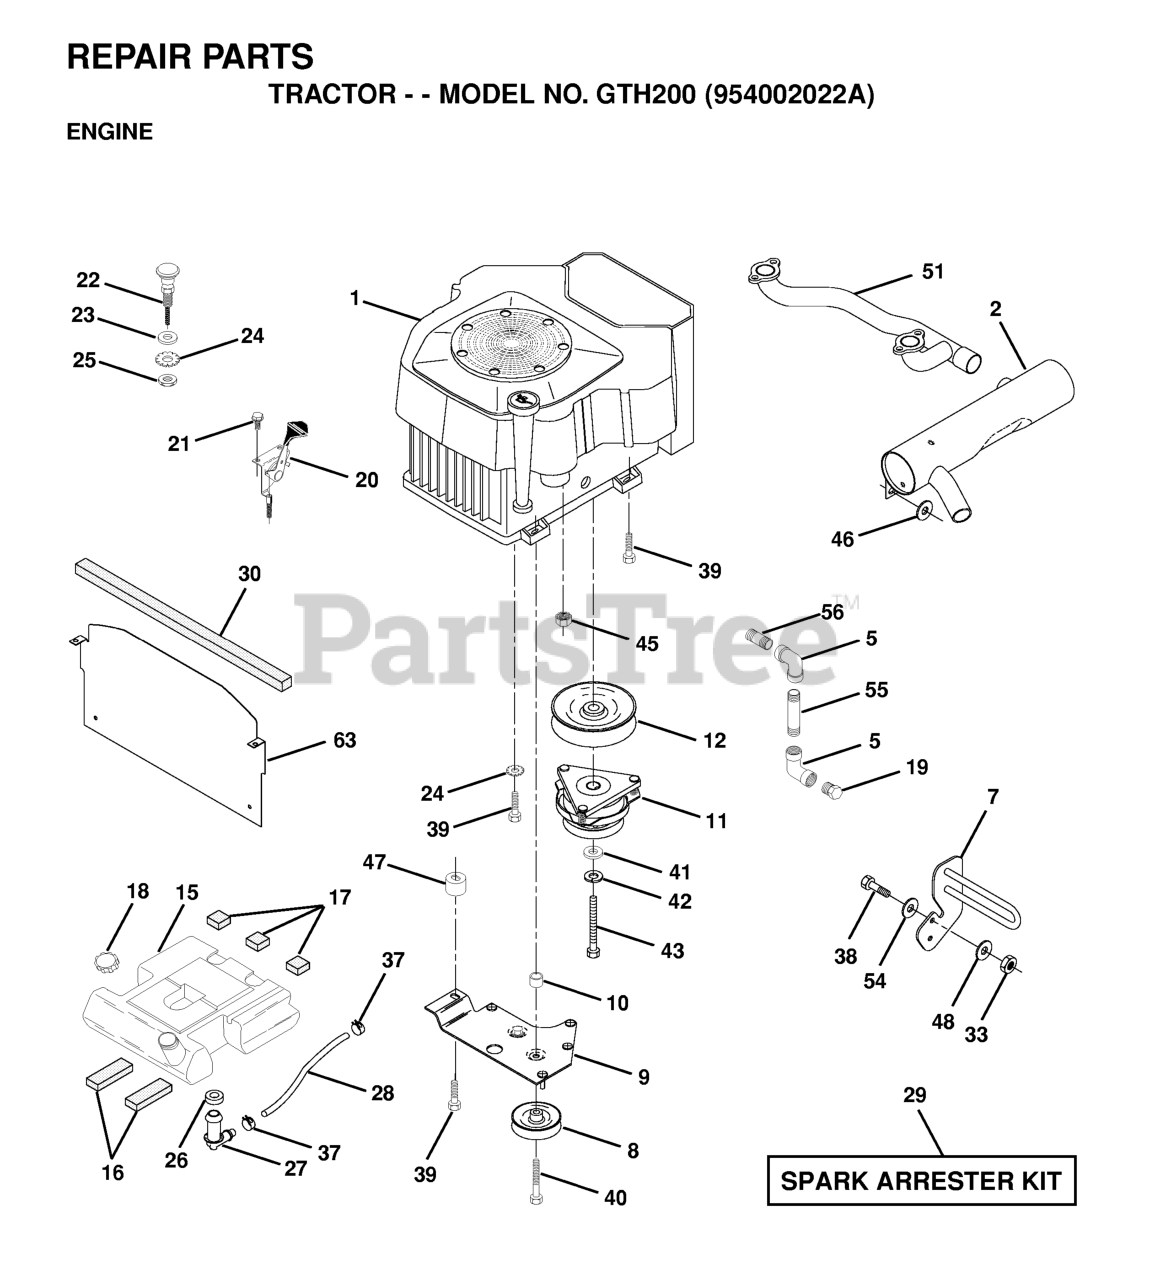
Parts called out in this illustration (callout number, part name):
2	MUFFLER VGT CYLINDER
5	ELBOW
7	MUFFLER GUARD
8	RP.IDLER GROOVED
9	BELT KEEPER
11	CLUTCH ELECTRIC
12	PULLEY ENG VGT ELECT CLUTCH
15	FUEL TANK REAR YT/GT
16	PAD IDLER TI
17	PAD-SPACER LT
18	FUEL CAP
20	THROTTLE CONTROL
21	SCREW LT
22	CHOKE CONTROL
23	WASHER
24	LOCKWASHER
25	NUT
26	BUSHING OUTLET T
27	STEM FUEL TANK
28	HOSE
29	SPARK ARRESTOR
30	FOAM-STRIP LT
33	NUT
37	HOSE CLAMP
38	BOLT
39	SCREW TT 3/8-16X2-1/4 UNC
40	Screw TT 3/8-16 x 4 unc
42	LOCKWASHER
43	BOLT
45	NUT FLANGE 1/4-20 STARTER NUT
46	WASHER
47	SPACER.ENGINE.CV22.ROUND.PM
48	Washer 13/32 x 1-1/4 x 7 Ga.
51	PIPE CROSSOVER
55	NIPPLE, PIPE 3/8NPT X 4-1/2
56	NIPPLE, PIPE 3/8 NPTX1.00
63	SHIELD, HEAT VGT YP/HUSQ
